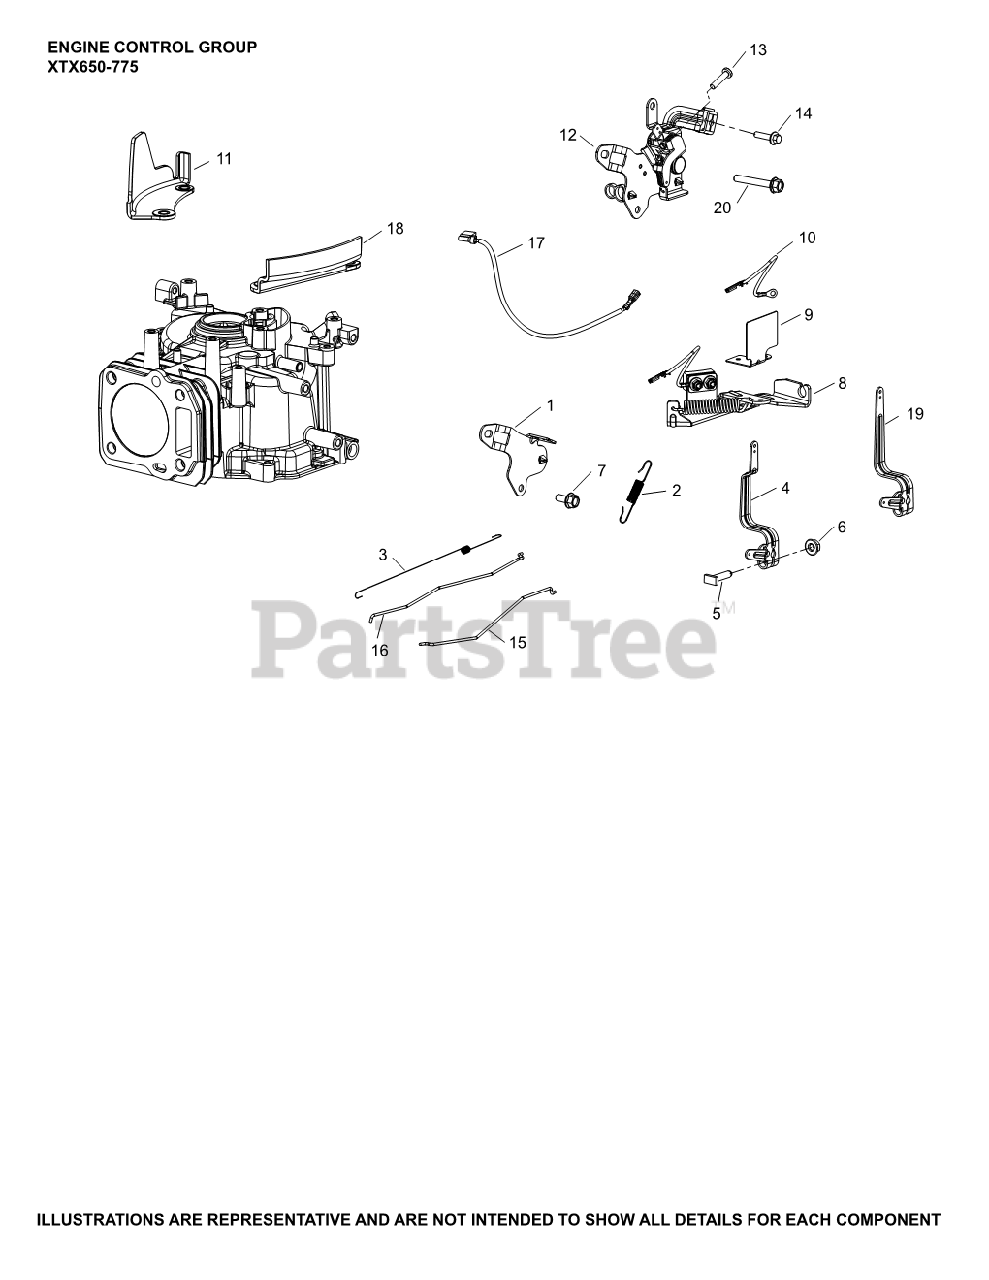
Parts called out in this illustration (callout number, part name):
2	SPRING, GOV (3301-3800 RPM)
3	SPRING, LINKAGE
5	SCREW, RECTANGLE HEAD (M6)
6	NUT, HEX FLANGE (M6) - USE 14 100 16-S
11	GUARD, FINGER
12	CONTROL ASSY, REMOTE VARIABLE SPEED USE 14 536 18-S
13	SCREW, #25 6-LOBE PAN HD (M5)
14	SCREW, (M5) HEX FLANGE
15	LINKAGE, CHOKE
16	LINKAGE, GOVERNOR
18	GUARD, FINGER
19	LEVER, GOVERNOR-USE 14 090 37-S
20	SCREW, HEX FLANGE (M6) (CKY)
